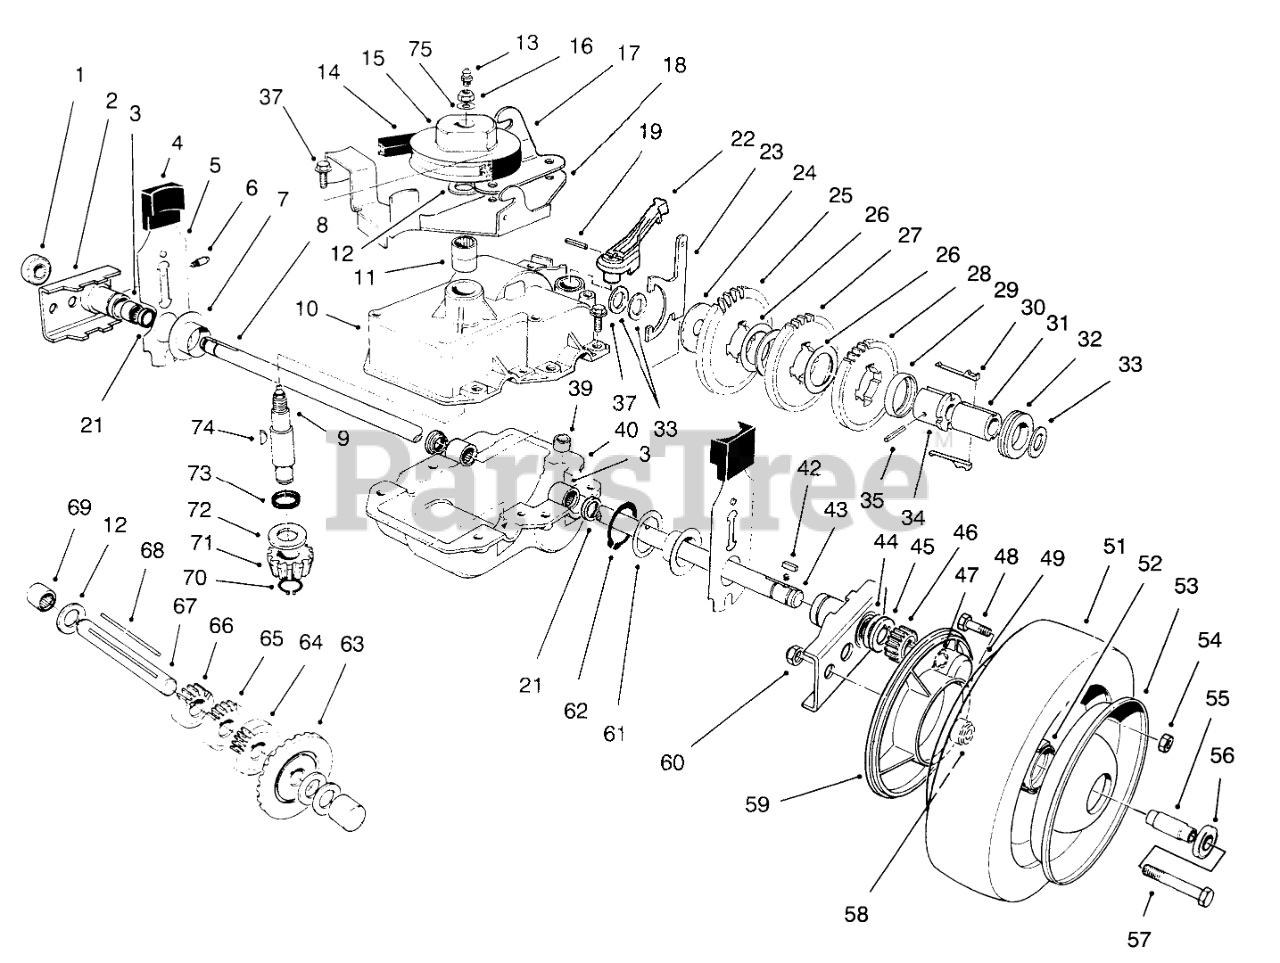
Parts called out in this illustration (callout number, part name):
1	BEARING-WHEEL
2	Pivot Arm Assembly (Incl. Ref. #1, 3, 6 & 21)
3	BEARING-ROLLER
4	KNOB-ARM
5	REAR SPRING ARM ASM
7	CAP-END
8	SHAFT-OUTPUT
9	Shaft-Input (Incl Ref. #13)
10	Upper Case Assembly (Incl. Ref. #11 & 73)
11	BEARING-NEEDLE
12	WASHER-THRUST
13	FITTING-GREASE, ZERK
14	V-BELT
15	PULLEY
16	NUT-HEX
17	Bracket-Traction Engage
18	Belt Guide Bracket
19	PIN-COIL
21	SEAL-OIL
22	LEVER-SHIFT
23	YOKE-SHIFT
24	WASHER
26	WASHER
27	GEAR-42T
28	GEAR-38T
29	RETAINER-KEY
30	KEY-SHIFT
31	SLEEVE
32	COLLAR-SHIFT
33	WASHER-PLAIN
34	SLEEVE-GEAR
35	PIN-GROOVE
37	SCREW-HWHTF
39	BUSHING-YOKE
40	CASE-GEAR, LOWER
43	SPRING-COMPRESSION
44	WASHER-THRUST, OUTER
45	WASHER-THRUST, OUTER
46	GEAR-PINION
47	RING-RETAINING
48	SCREW-HH
49	Wheel-Half
52	HUB-BEARING
53	Wheel-Half
54	NUT-LOCK, NI
55	SPACER-BEARING
56	BEARING-WHEEL
57	SCREW-HH
58	SPACER-COVER, WHEEL
59	COVER-WHEEL
60	NUT-LOCK, CONE
61	WASHER
62	RING-RETAINING
63	GEAR-BEVEL
64	GEAR-18T
65	GEAR-14T
66	GEAR-12T
67	SHAFT-INTERMEDIATE
69	BEARING-NEEDLE, CLOSED
70	RING-RETAINING
71	PINION-BEVEL
72	WASHER-THRUST
74	KEY-WOODRUFF
75	WASHER-FLAT
